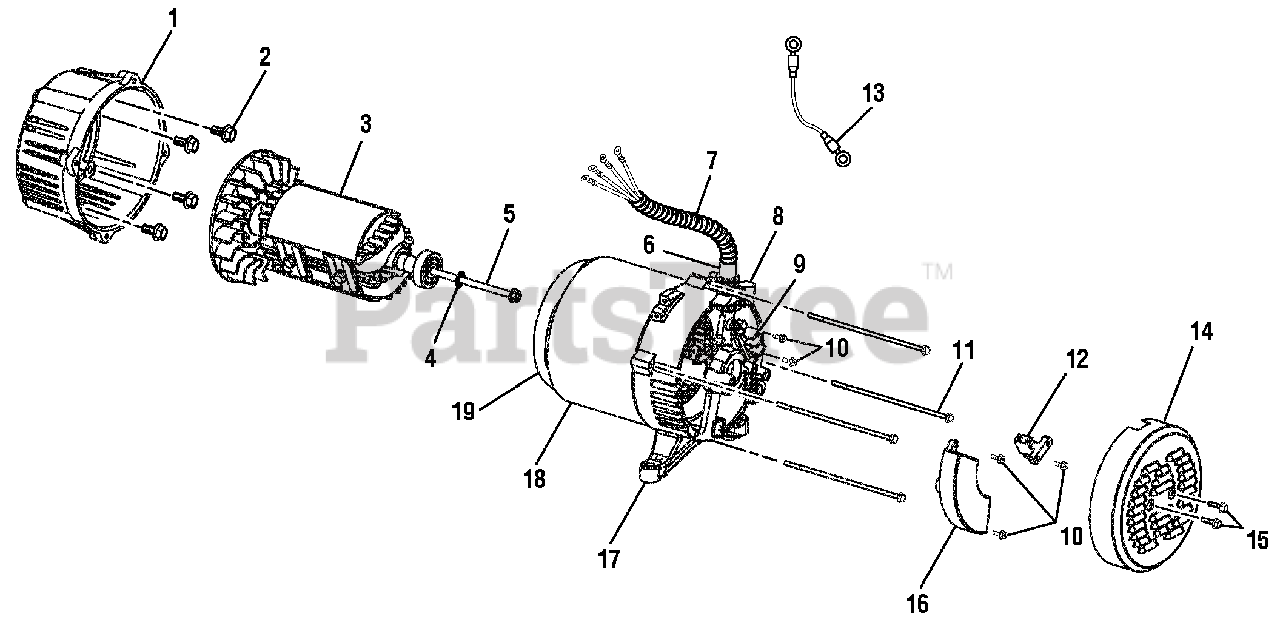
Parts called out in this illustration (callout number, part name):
1	Adaptor Housing
2	Bolt (3/8-16 x 1.25 in.)
4	Lock Washer (5/16)
5	Rotor Bolt
6	Rubber Boot
7	Wiring Harness
8	Generator Head Assembly
9	Terminal Block
10	Bolt (M5 x 16 mm)
11	Bolt (Stator)
12	Brush Assembly
13	Bonding Wire
14	Brush Cover
15	Bolt (M5 x 10 mm)
16	Automatic Voltage Regulator
17	Bearing Housing
18	Generator Head Cover
